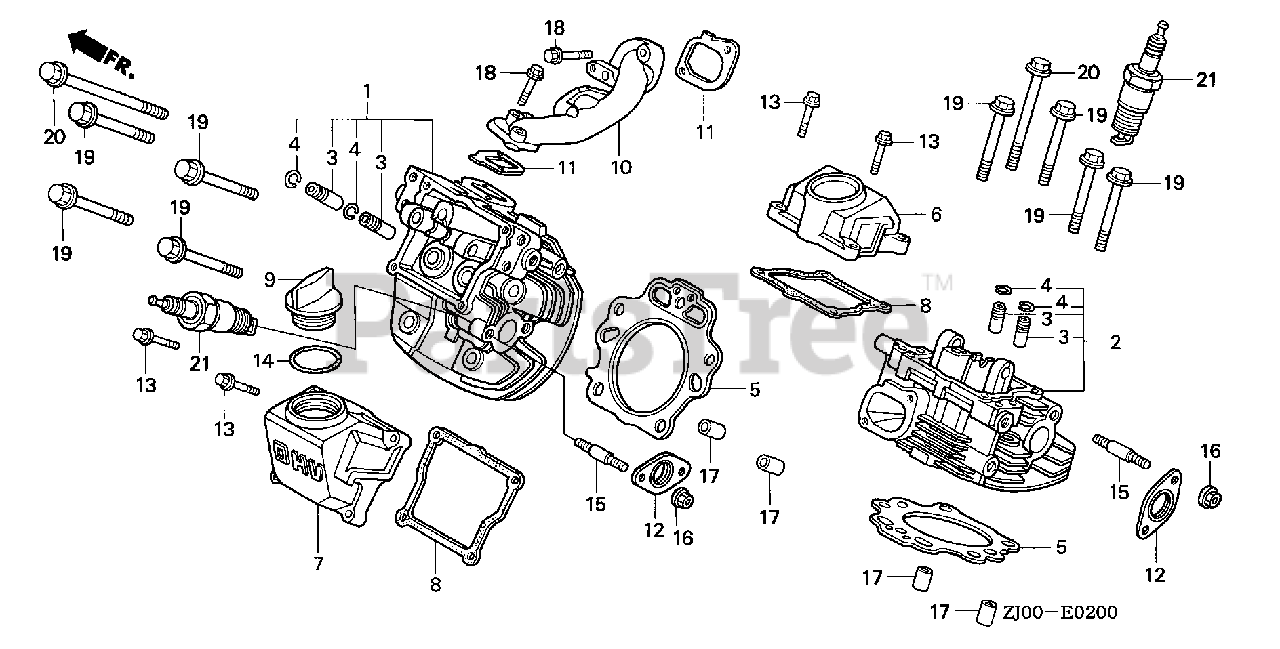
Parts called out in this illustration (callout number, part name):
1	CYLINDER HEAD, R.
2	CYLINDER HEAD, L.
3	GUIDE, EX. VALVE (OVER SIZE)
4	CLIP, VALVE GUIDE
5	GASKET, CYLINDER HEAD
6	COVER, HEAD
7	COVER, HEAD FILLER (NOT AVAILABLE)
8	GASKET, HEAD COVER
9	CAP, OIL (YELLOW)
10	MANIFOLD, IN.
11	GASKET, IN. MANIFOLD
12	GASKET, EX. PIPE
13	BOLT, FLANGE (6X25) (CT200)
14	O-RING (26X2.7)
15	BOLT, STUD (8X25)
16	NUT, FLANGE (8MM)
17	PIN, DOWEL (12X20)
18	BOLT, FLANGE (6X32)
19	BOLT, FLANGE (10X75)
20	BOLT, FLANGE (10X130)
21	SPARK PLUG (BPR2ES) (NGK)
21	SPARK PLUG (BPR4ES) (NGK)
21	SPARK PLUG (W14EPR-U) (DENSO)
21	SPARK PLUG (BPR6ES) (NGK)
